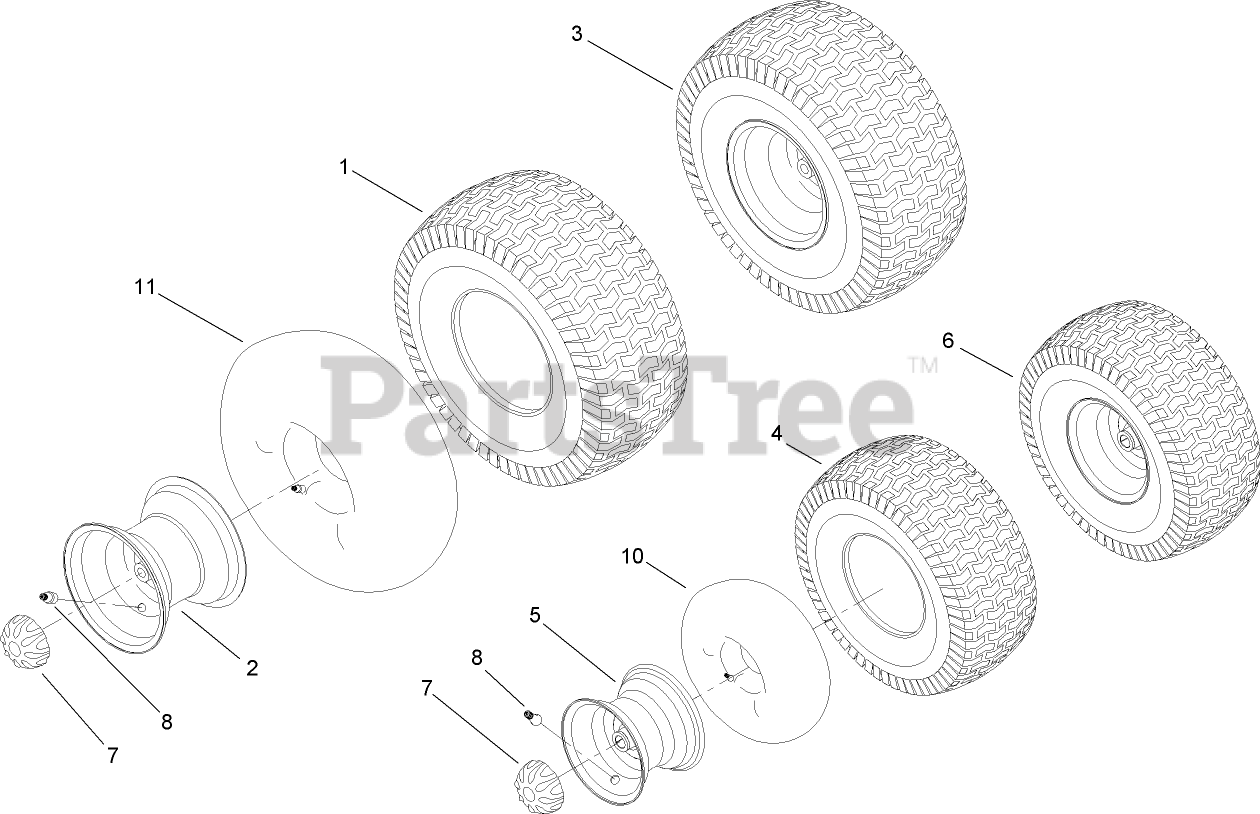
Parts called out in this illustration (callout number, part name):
1	TIRE-MULTI TRAC
4	TIRE-FRONT
5	RIM-WHEEL, FRONT
7	CAP-HUB
8	VALVE-AIR, TUBELESS
10	TUBE-INNER
11	TUBE-INNER
